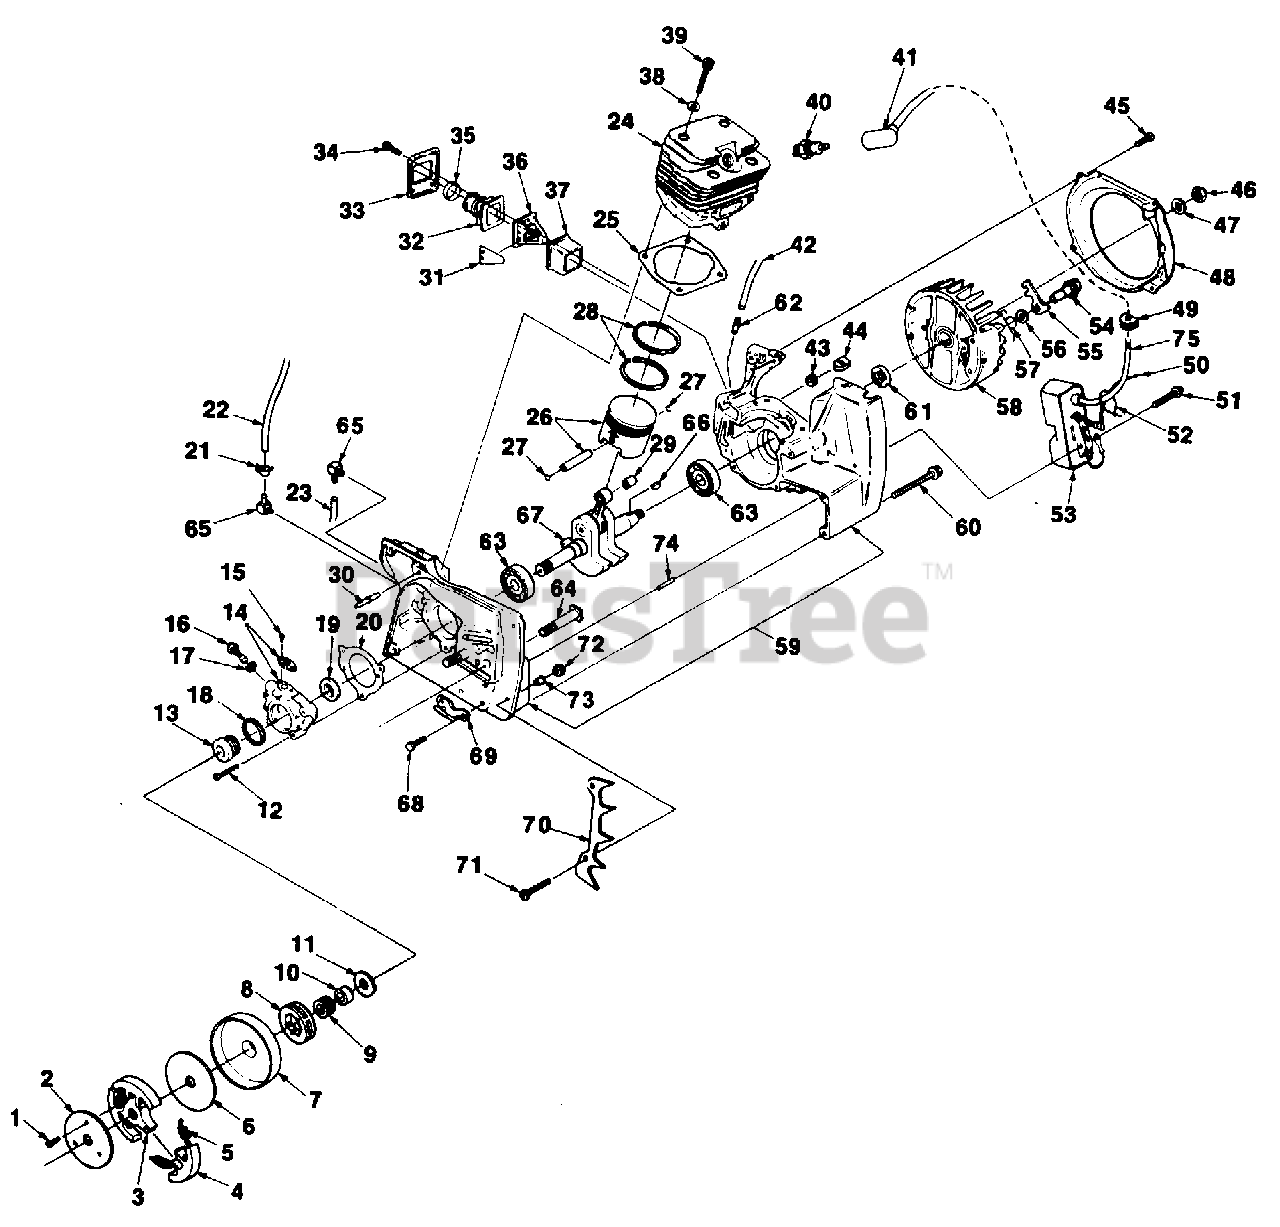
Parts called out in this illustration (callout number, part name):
1	SCREW- Pan hd. (8-32 x 3/8")
2	COVER- Clutch
3	SPIDER- Clutch
4	SHOE- Clutch
5	SPRING- Clutch
6	WASHER- Thrust
7	DRUM & HUB
8	SPROCKET 3/8" pitch 7 tooth
9	BEARING- Needle
10	RACE- Inner
11	WASHER- Thrust
12	SCREW- Fil. hd. (10-24 x 7/8")
13	WORM- Oil pump
14	PUMP- Automatic oil
15	SCREW- (4-40 x 1/4")
16	SCREW- Cam
18	SEAL- Felt
19	SEAL
22	TUBING 5" (manual delivery)
23	TUBING- 6 3/4" (auto oil pick-up)
24	CYLINDER
27	RING- Retaining
28	PISTON- Ring
29	NEEDLE- Bearing (after lot #E286)
30	PIN- Dowel
32	CONNECTOR- Carburetor
33	RETAINER- Reed valve
34	SCREW- Washer hd. (8-32 x 5/8")
35	STIFFNER- Connector
36	SEAT- Reed valve
37	RETAINER- Reed
38	WASHER- Conical
39	SCREW- Soc hd. (10-24 x 1 1/8")
40	SPARK PLUG (DJ7Y)
41	TERMINAL- Spark plug
42	TUBING- 4 3/4"
43	NUT- Centerlock (10-24)
44	RETAINER- Nut
45	SCREW- Pan hd. (6-32 x 3/8")
46	NUT- Lock (3/8-24)
47	WASHER- Flat
48	SCROLL- Air guide
49	GROMMET
50	SWITCH & LEAD
51	SCREW- Hex Sems (10-24 x 7/8")
52	CLAMP- Wire
53	MODULE
54	BOLT- Shoulder
55	PAWL- Starter
56	WASHER- Flat
57	SPRING- Starter pawl
59	CRANKCASE
60	SCREW- (10-24 x 1 3/4")
61	SEAL
62	FITTING
63	BEARING- Ball
64	BOLT- Guide bar
65	FITTING
66	KEY- Woodruff
67	CRANKSHAFT
68	SCREW- Hex Sems (8-32 x 1/2")
69	STOP- Chain
70	KIT- Spiked bumper
71	SCREW- (10-24 x 1/2")
73	WASHER- Sealing
74	PIN- Dowel
75	LEAD- High tension
